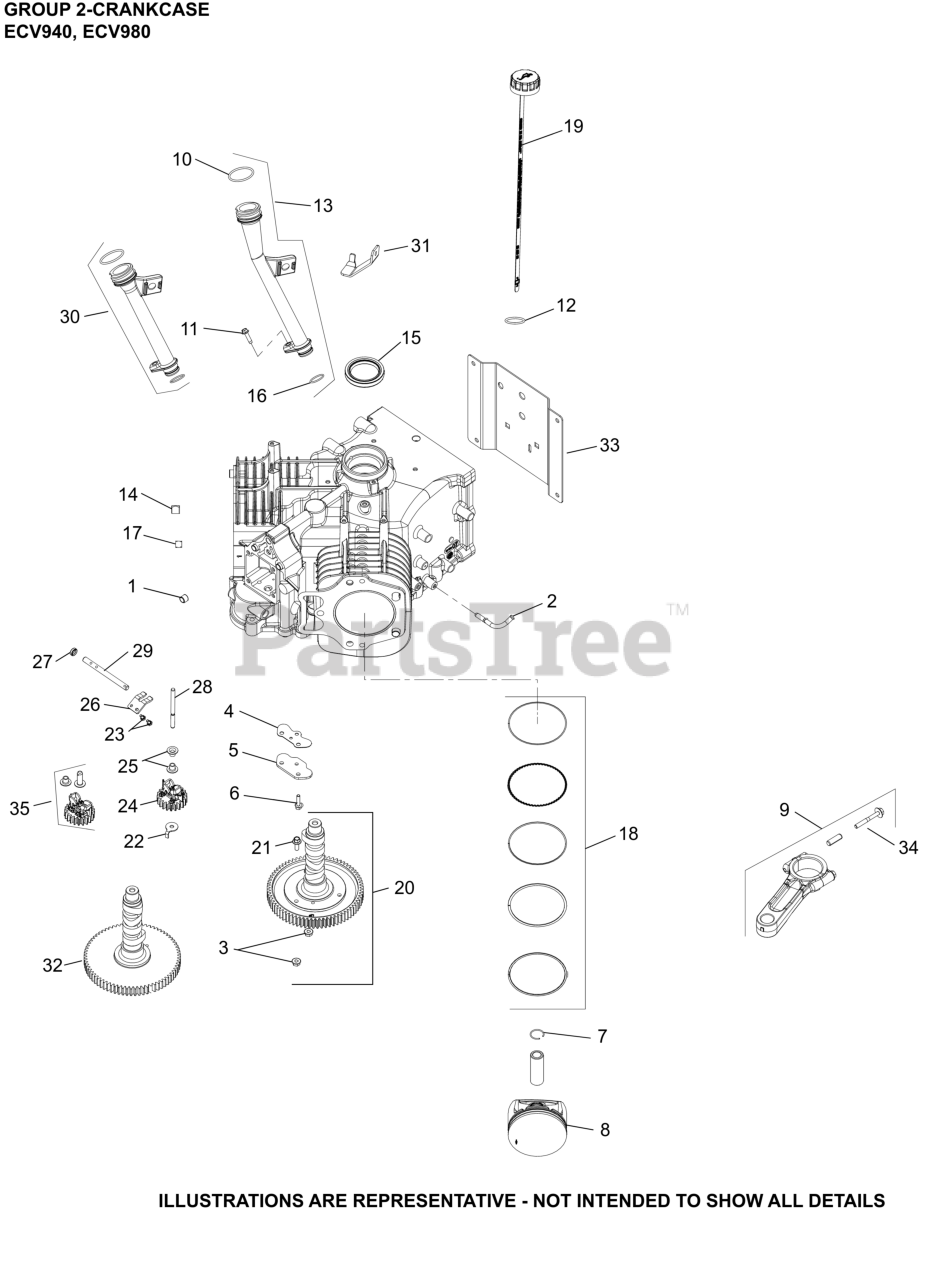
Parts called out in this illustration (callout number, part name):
2	FITTING, PULSE PUMP
4	GASKET, LIFTER FEED COVER
5	KIT, COVER, LIFTER FEED
6	SCREW, HEAVY HEX FLANGE
7	RETAINER, PISTON PIN
8	KIT, PISTON (STD)
8	KIT, PISTON (0.25 OS)
8	KIT, PISTON (0.50 OS)
9	CONNECTING ROD ASSEMBLY
10	O-RING, UPPER OIL FILL TUBE
11	SCREW, THD FRM-USE 25 086 473-S
12	O-RING, DIPSTICK
13	KIT,OIL FILL TUBE
14	PIN, LOCATING
15	SEAL, OIL (RIGHT-HAND HELIX, FWE)
17	PLUG, CTSK PIPE 1/8"
18	RING, SET PISTON (STD) "STYLE B ONLY"
19	DIPSTICK ASSEMBLY
32	KIT, CAMSHAFT
34	KIT, ROD BOLTS
